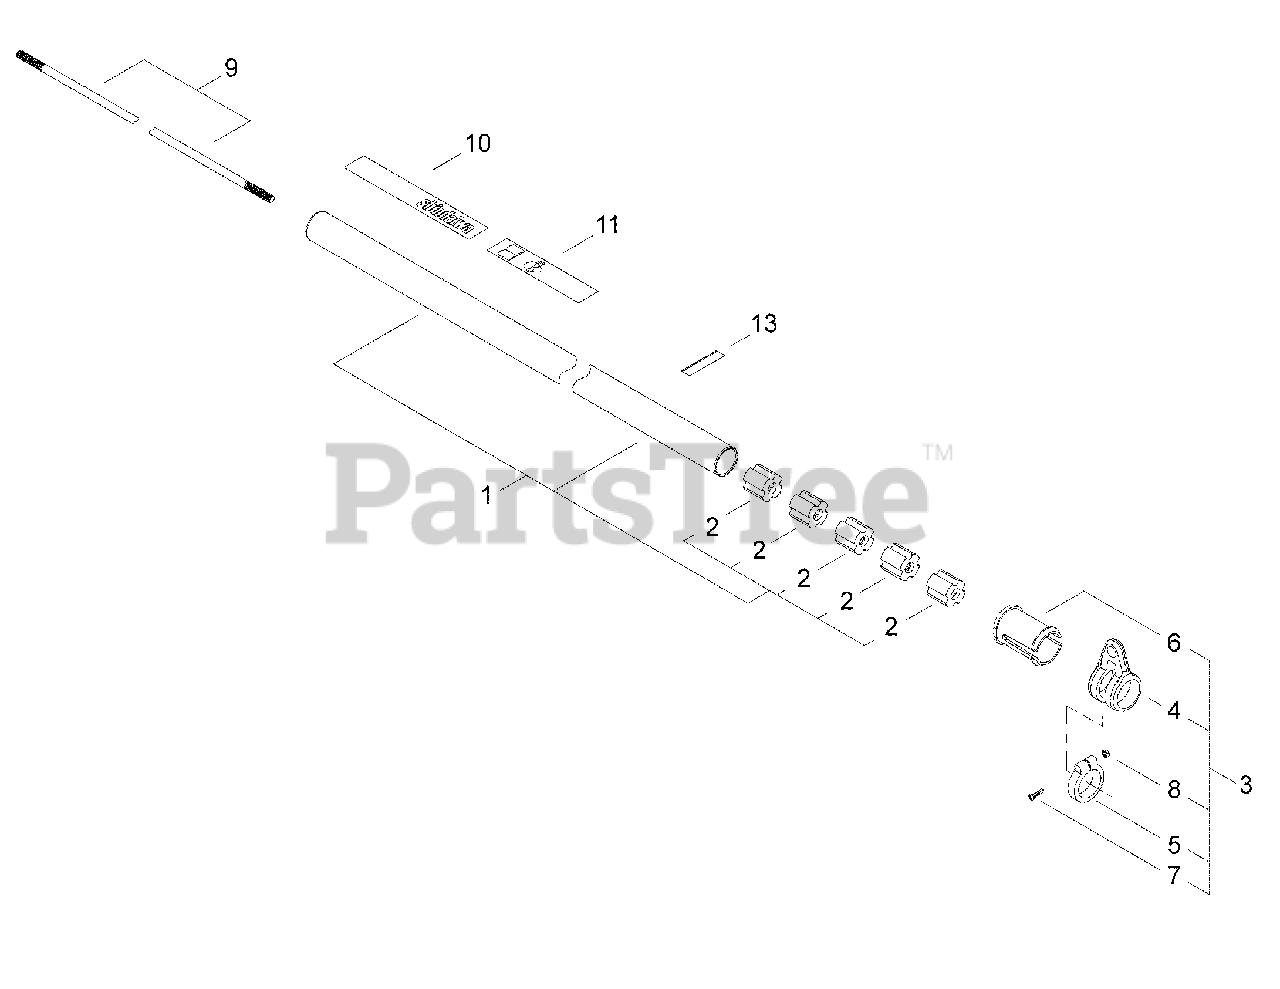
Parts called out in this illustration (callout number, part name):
1	MAIN PIPE ASSY
2	BUSHING
3	HANGER ASSY
4	HANGER
5	CLAMP
6	COLLAR
7	SCREW - 4X16
8	NUT - 4
9	PIPE, MAIN
10	LABEL - TRADE
11	LABEL - CAUTION
13	LABEL - HANDLE LOCATION
